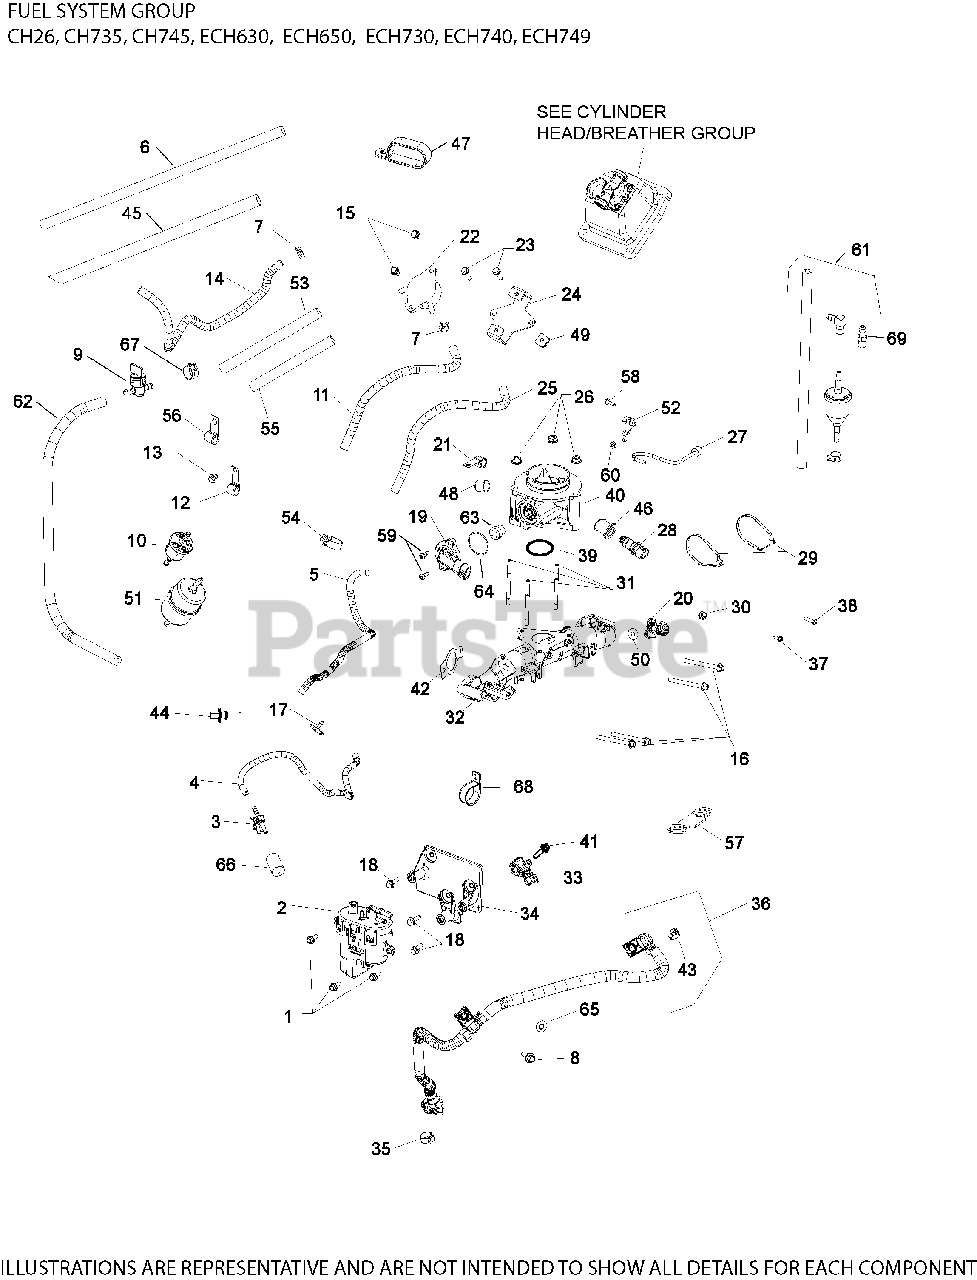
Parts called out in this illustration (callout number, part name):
1	SCREW, FLG M6X1.0X16
2	KIT, FUEL PUMP MODULE USE 25 393 16-S
4	HOSE, EVAPORATIVE (15.0)
5	SLEEVE, ANTI-ABRASION
7	CLAMP, HOSE (KM)-USE 25 237 31-S
8	SCREW, FLG M6x1.0x20
10	FILTER, FUEL
11	HOSE, FUEL LOW PERMEATION
16	SCREW, FLG M6X1.0X60
17	TEE CONNECTOR
18	SCREW, THREAD FORMING
19	SENSOR, THROTTLE POSITION
20	INJECTOR, FUEL
21	CLIP, CABLE
31	STUD,M6X1.0X84
32	KIT, MANIFOLD
34	BAFFLE, FUEL MODULE
35	CLAMP, HOSE
36	RAIL, FUEL ASSEMBLY (HORIZONTAL COMMAND)
40	BODY, THROTTLE ASM W/ PIN (30)
42	GASKET, INTAKE MANIFOLD USE 24 041 79-S
43	CLAMP, OETIKER
48	CAP, MASKING
50	KIT, FUEL INJECTOR O-RING
55	SLEEVE, ANTI ABRASION-USE 25 431 12-S
63	MAGNET ASSEMBLY, TPS
64	O-RING, TPS SENSOR
65	CLIP, RETAINER
